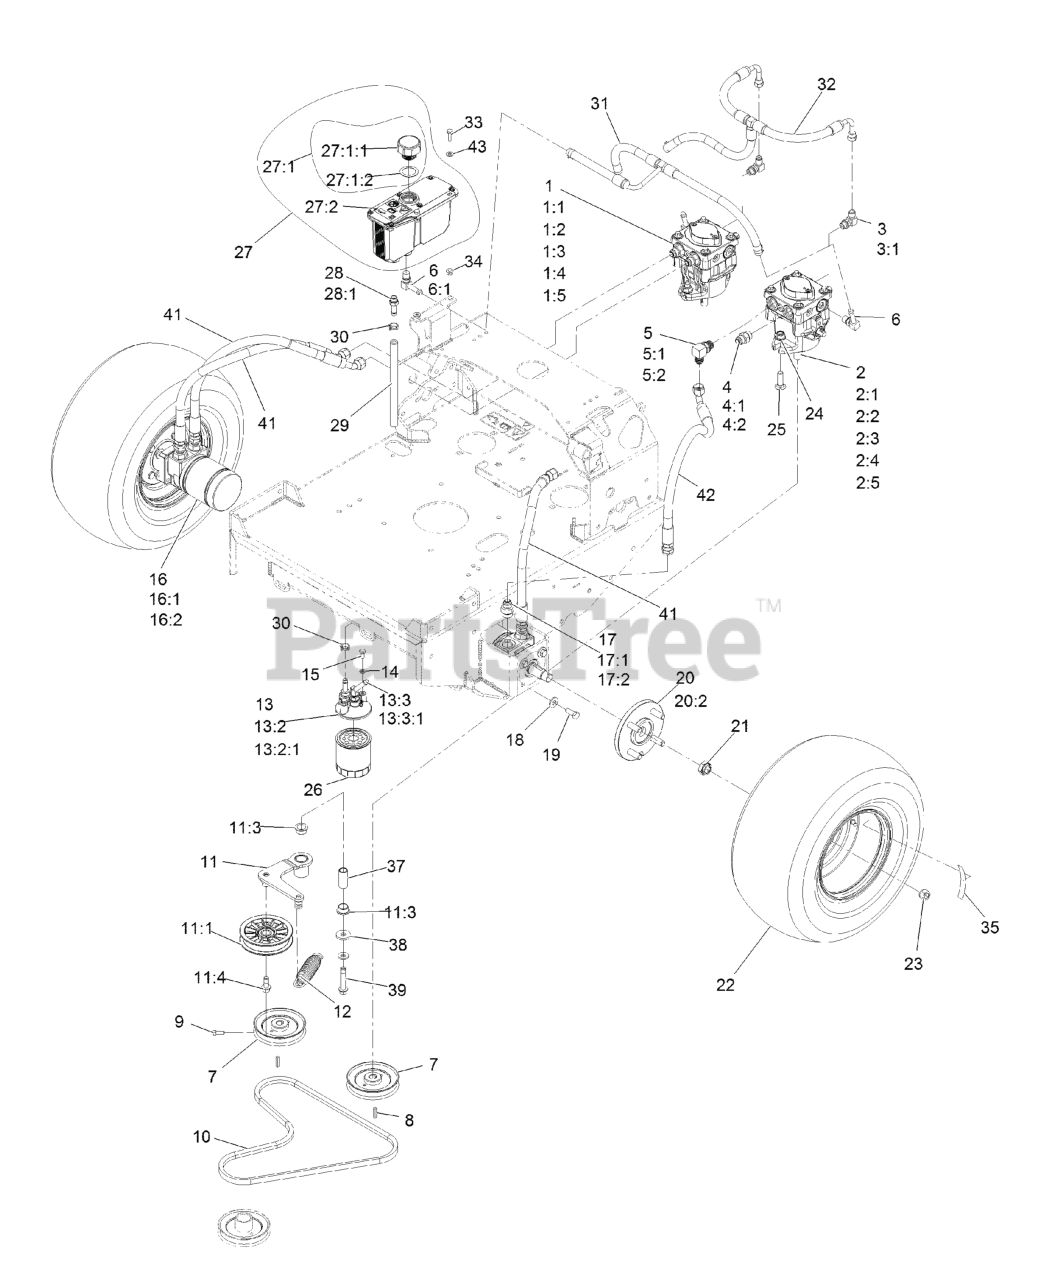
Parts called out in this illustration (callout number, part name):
1	PUMP-HYD PE RH TTH
1:1	INPUT SHAFT KIT
1:2	BEARING-THRUST
1:3	CYLINDER BLOCK KIT
1:4	SEAL OVERHAUL KIT
1:5	KIT, 10CC PUMP KIT
2	PUMP-HYD PE LH TTH
2:1	INPUT SHAFT KIT
2:2	BEARING-THRUST
2:3	CYLINDER BLOCK KIT
2:4	SEAL OVERHAUL KIT
2:5	KIT, 10CC PUMP KIT
3	FITTING-ELBOW, 90 DEG
3:1	O-RING
4	FITTING-STRAIGHT
5	FITTING-90 DEG
6	FITTING-ELBOW, 90
6:1	O-RING
7	SHEAVE ASM
9	SCREW-SET, SQH
10	BELT
11	ASM, PUMP IDLER
11:1	PULLEY-IDLER, FLAT
11:3	BUSHING-FLANGE
11:4	SCREW-HFH
12	SPRING-EXTENSION
13	ASM, FILTER HEAD
13:2	ADAPTER-STRAIGHT
13:2:1	O-RING
13:3	FITTING-BARBED, 45 DEG
13:3:1	O-RING
14	WASHER-LOCK
15	SCREW-HH
16	HYD MOTOR ASM
16:1	SEAL KIT
16:2	BEARING AND SEAL KIT
17	FITTING-STRAIGHT
17:1	O-RING
18	WASHER-BELLEVILLE
19	SCREW-HH
20	WHEEL HUB ASM
20:2	STUD-WHEEL
21	NUT-LOCK
22	ASM, DRIVE TIRE
23	NUT-LUG
24	NUT-HF, NI
25	BOLT-CARR
26	FILTER-25 MICRON, BI-DIRE
27:1	Reservoir-HYD
27:1:1	Cap-Reservoir, HYD
27:1:2	GASKET-CAP
27:2	DECAL-WARNING
28	ADAPTER-STRAIGHT
28:1	O-RING
29	HOSE-CHARGE
30	CLAMP-HOSE
31	HOSE, CASE
32	HOSE, CHARGE
33	SCREW-HH
34	NUT-HHF
35	DECAL-TORQUE WHEEL LUG-HU
37	PIVOT, IDLER
39	SCREW-HHF W/ PATCH
41	HOSE,HYDRAULIC W/COVER
42	HYD HOSE ASM
43	WASHER-FLAT
